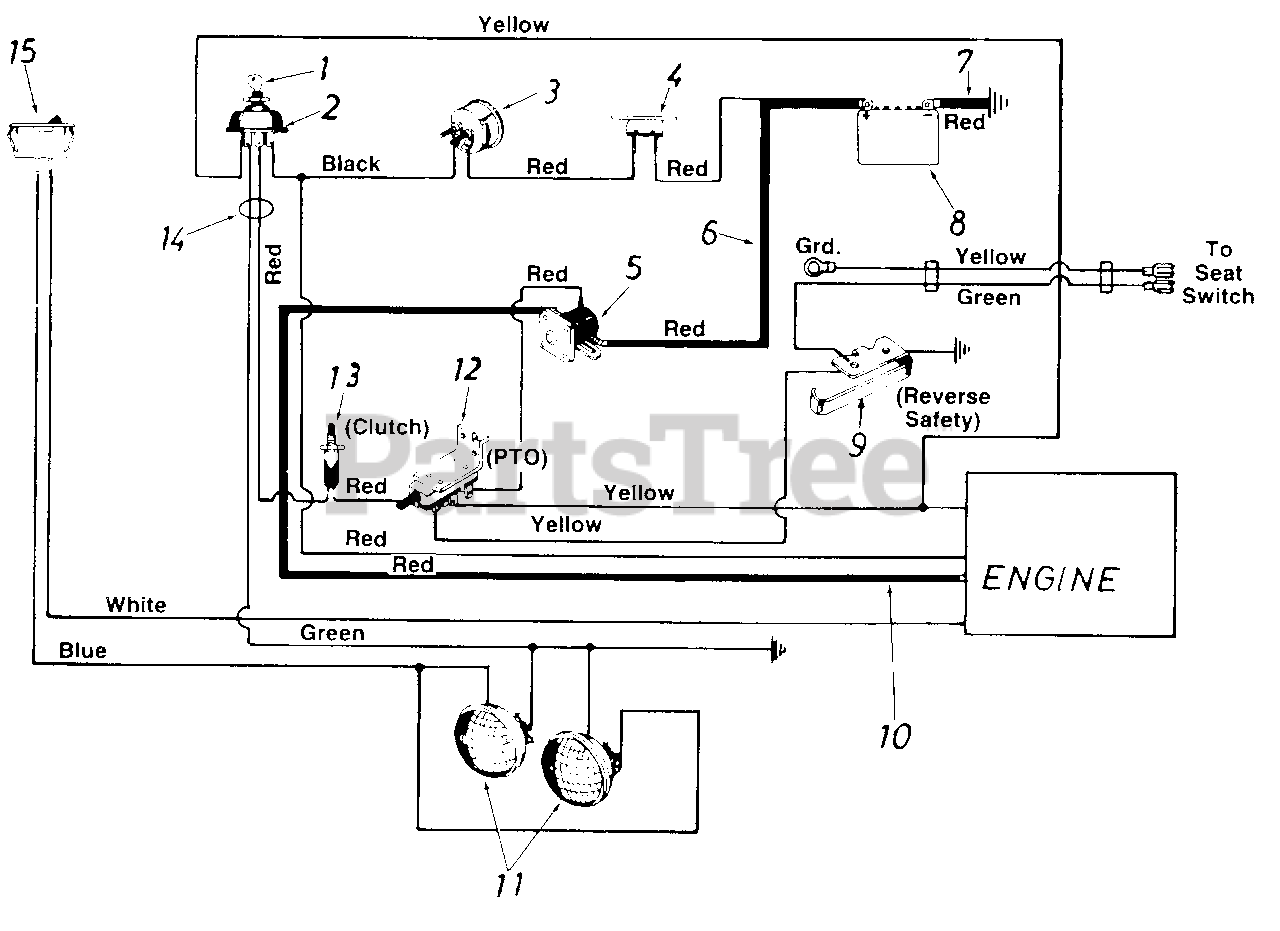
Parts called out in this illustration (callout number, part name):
1	Ignition Key
2	Ignition Switch
3	Ammeter
4	Circuit Breaker
5	Solenoid
6	Electric Wire
7	Electric Wire
8	Battery
9	Spring Switch
10	Electric Wire
11	Headlights
12	Safety Switch
13	Safety Switch
14	Wire Harness
15	Light Switch
